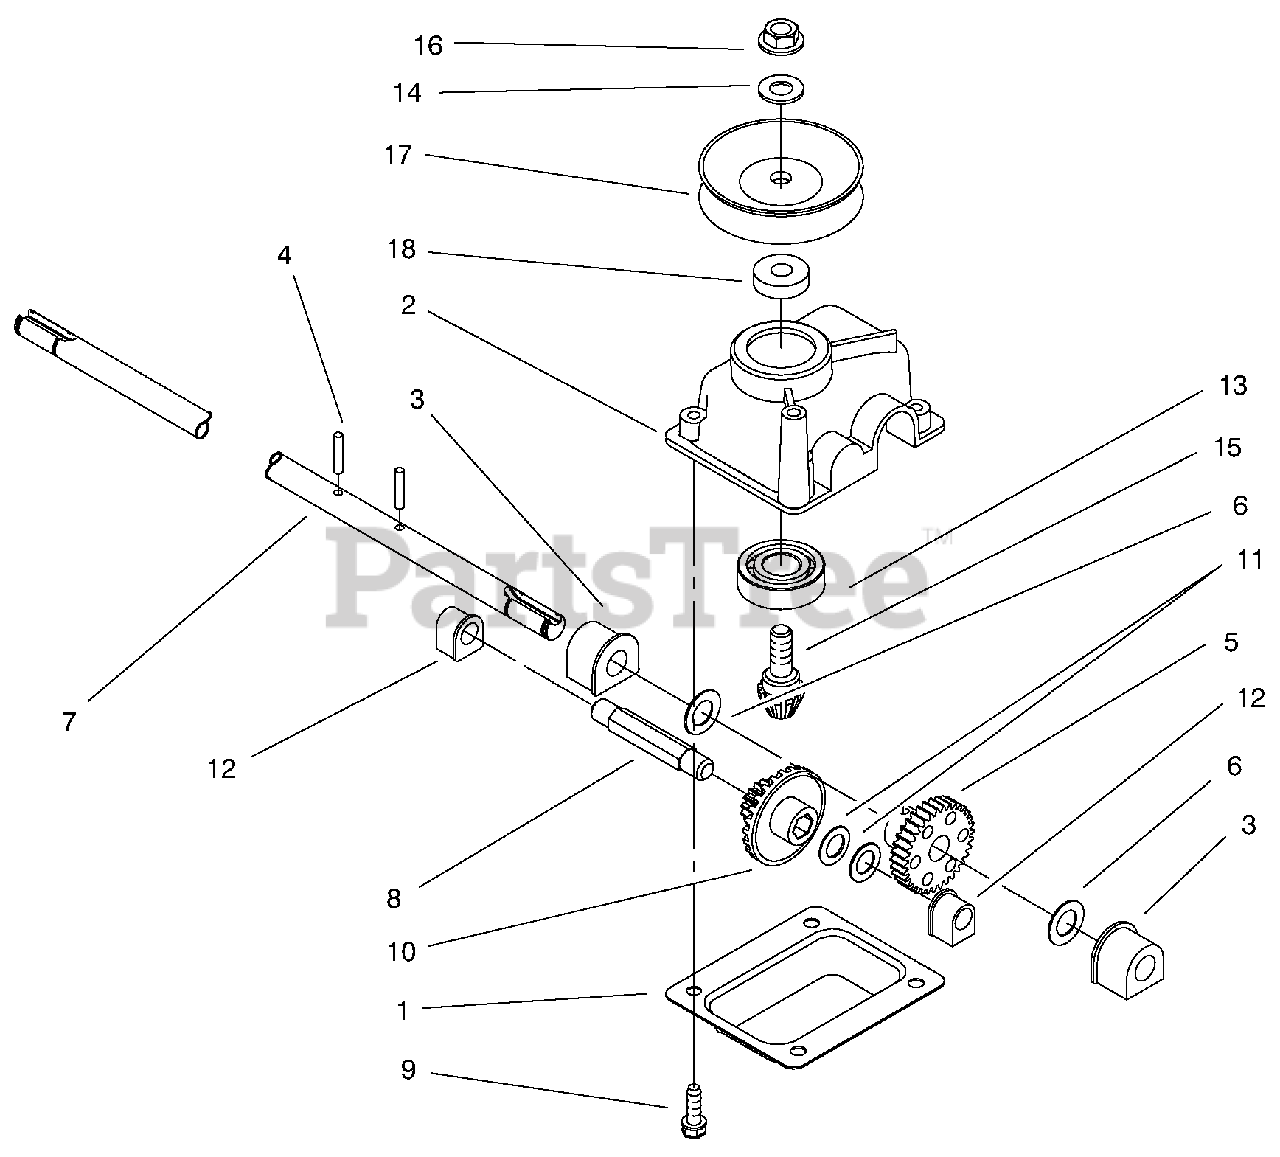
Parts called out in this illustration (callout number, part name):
1	Cover-Gear Case
2	Gearcase-Upper Ss
3	Bushing-Output
4	Pin-Spirol
5	Gear-34t
6	Washer-Thrust
7	Shaft-Output
8	Shaft-Intermediate
9	Screw-TAP
10	15 T Pinion
11	Washer-Thrust
13	Bearing-Ball
14	Washer-Flat
15	Gear-Pinnion
16	Nut-Lock
17	Pulley-Half
18	Spacer-Pulley
